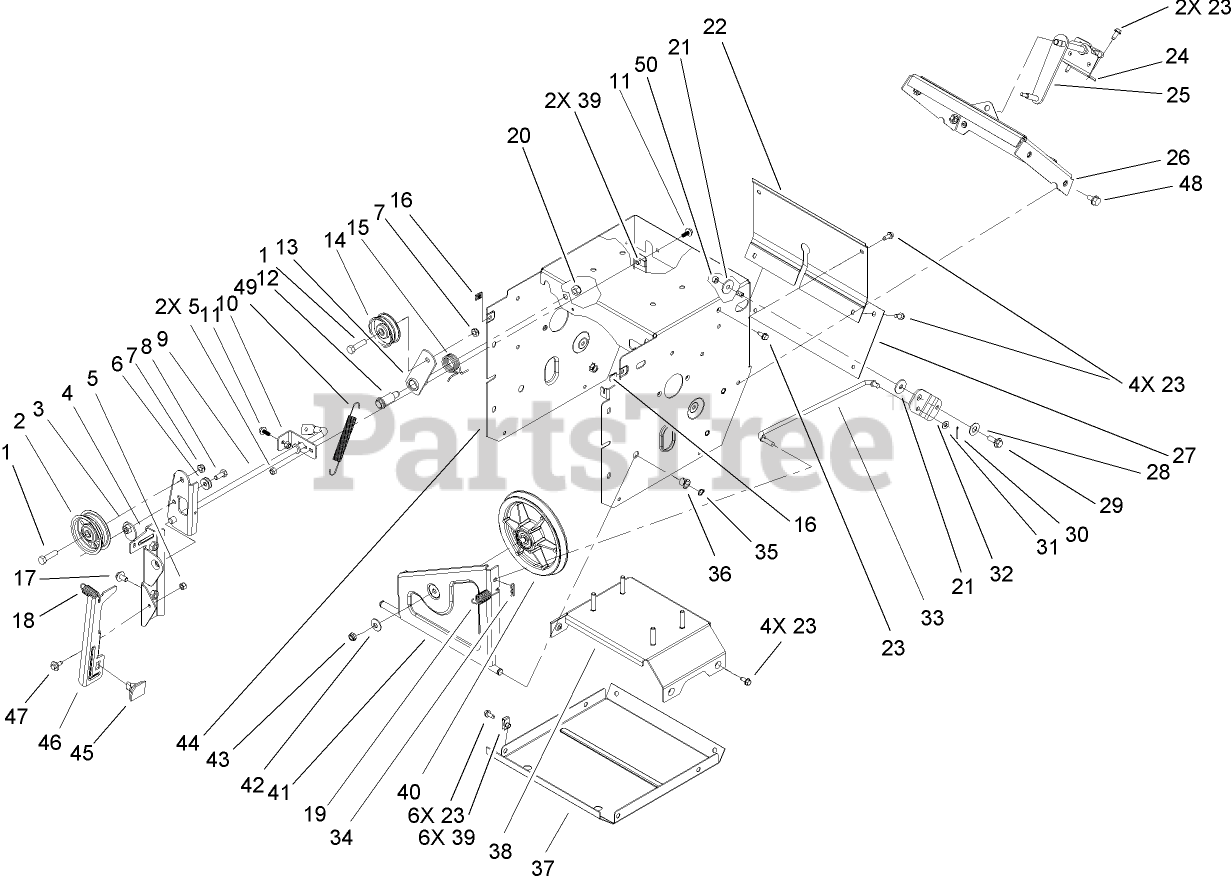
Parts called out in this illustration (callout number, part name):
1	SCREW-HH
2	PULLEY-IDLER
5	NUT-LOCK, NI
6	WASHER-BELLEVILLE
8	SCREW-HH
9	AUGER CLUTCH ASM
10	BRACKET-REAR, CLUTCH
11	SCREW-HHF
12	BOLT-SHOULDER
14	PULLEY-IDLER
16	NUT-SPEED
17	SCREW-HHF
18	SPRING-EXTENSION
19	SPRING-EXTENSION
20	NUT-LOCK, NI
21	WASHER-PIVOT
22	COVER-UPPER
23	SCREW-HWH
25	LEVER-CONTROL, TRACTION
27	COVER-LOWER
28	WASHER
29	SCREW-SHOULDER
30	PIN-COTTER
31	WASHER-PLAIN
32	BELLCRANK-DRIVE
33	LINK-CONTROL, SPEED
35	RING-RETAINING
36	BUSHING-NYLINER
37	PAN-BOTTOM
42	WASHER-BELLEVILLE
43	NUT-HEX
44	FRAME-TRACTION ASM
45	PAD-BRAKE
47	SCREW-SHOULDER
48	SCREW-HWHTF
50	NUT-LOCK, NI
